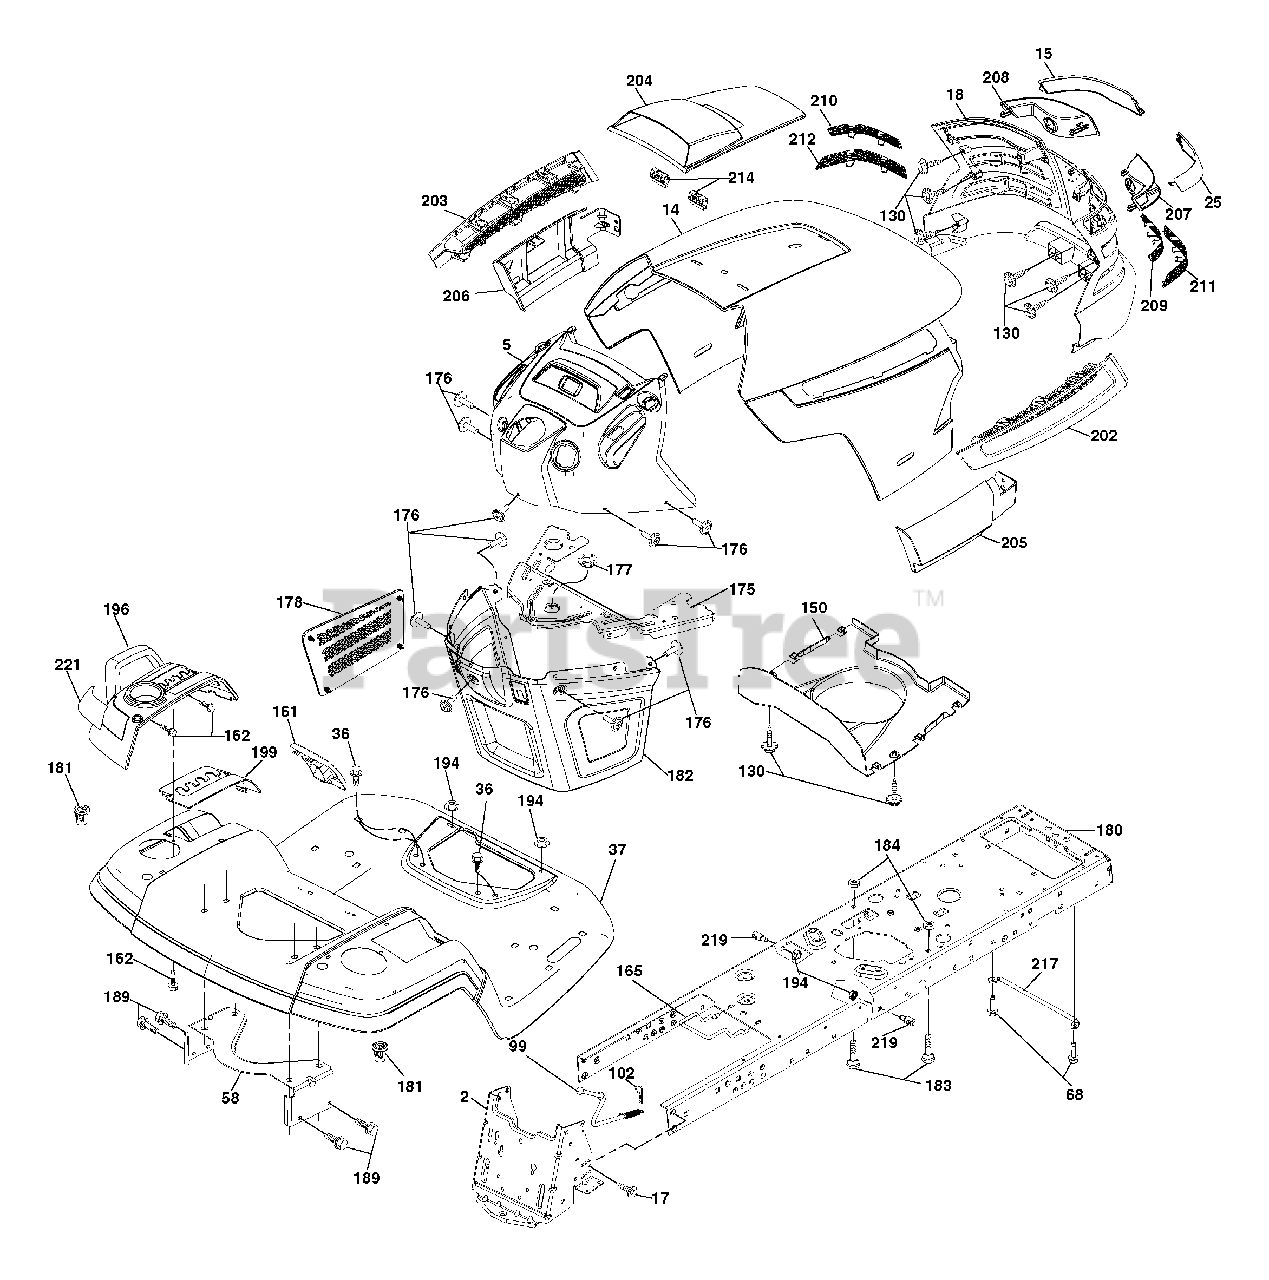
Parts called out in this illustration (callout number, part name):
2	Drawbar
14	Hood
17	Screw 3/8-16 x .75
18	Grille
36	Screw 5/16-18 x 3/4
37	Fender
58	Bracket Fender
68	Screw 5/16-18 x 1/2
99	Rod Bypass Asm.
102	Retainer Spring 1"
130	Screw 10 x 3/4 Single Lead-Hex
150	Duct Heat Hood
161	Console Fuel Window
162	Screw Hex Wsh Hi-Lo 1/4 x 1/2
165	Support Tank Rear
175	Crossmember
176	Screw 10-24 x 5/8 RND Qdrx
177	Bushing Steering
178	Cargo Asm. Net
180	Chassis
181	Bushing Mtg. Fender Crgo.
182	Dash Lower
183	Bolt 5/16-18 x 1/1/4
184	Spacer Fender
194	Nut Lock 5/16-18
195	Plug Hole Dash Lower
196	Console Asm. Deck Lift
199	Plate Deck Lift
202	Vent Side Hood RH
203	Vent Side Hood LH
204	Vent Asm Hood Top
205	Skirt Hood Side RH
206	Skirt Hood Side LH
209	Insert Hex Top RH
210	Insert Hex Top LH
211	Insert Hex Bottom RH
212	Insert Hex Bottom LH
214	Clip Retainer
217	Rod Pivot
219	Stud Fastner
221	Reflector LH
